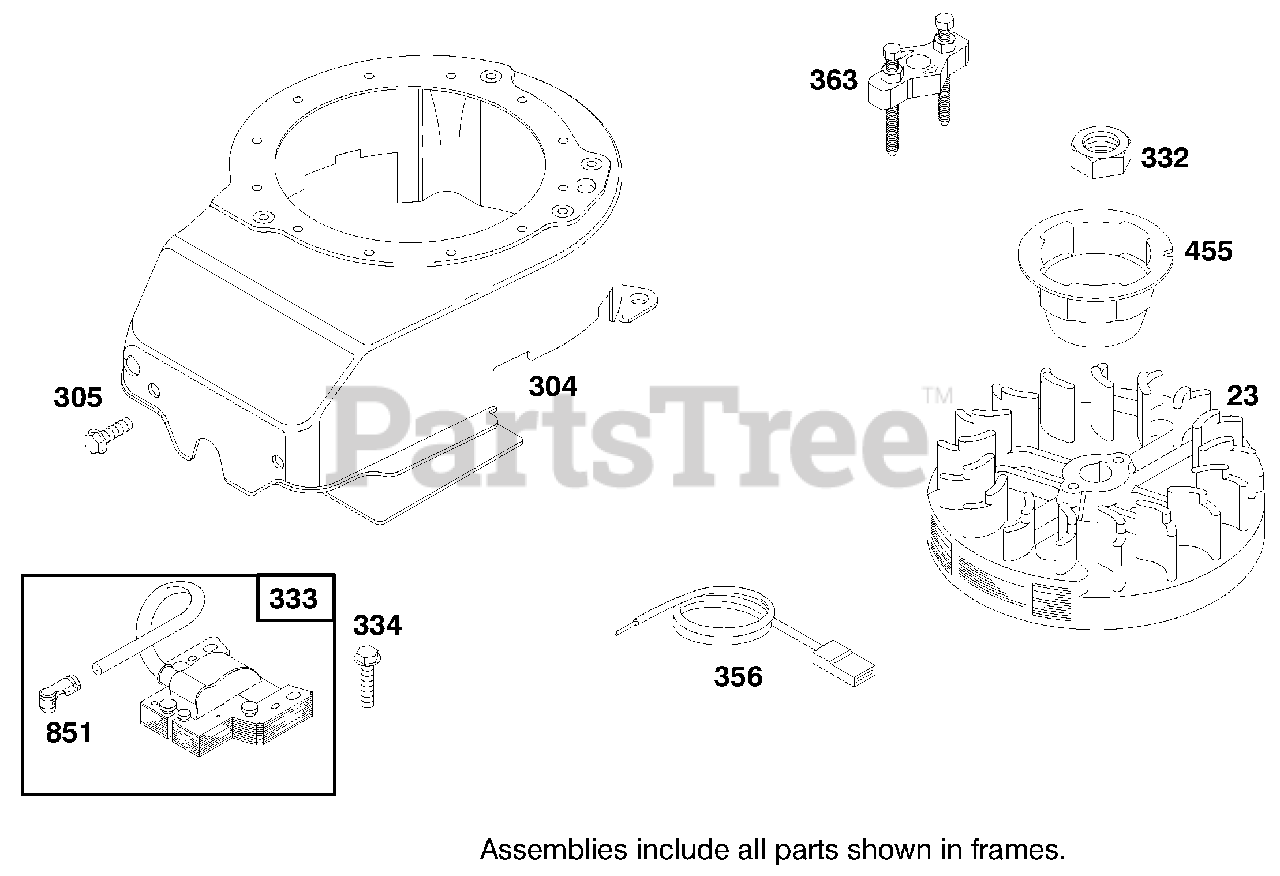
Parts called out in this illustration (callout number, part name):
23	Flywheel
304	Housing-Blower
332	Nut-Flywheel
333	Armature-Magneto
334	Screw-Sem
356	Wire-Ground
363	Flywheel Puller
455	Cup-Starter
851	Terminal-Ignition Cable
